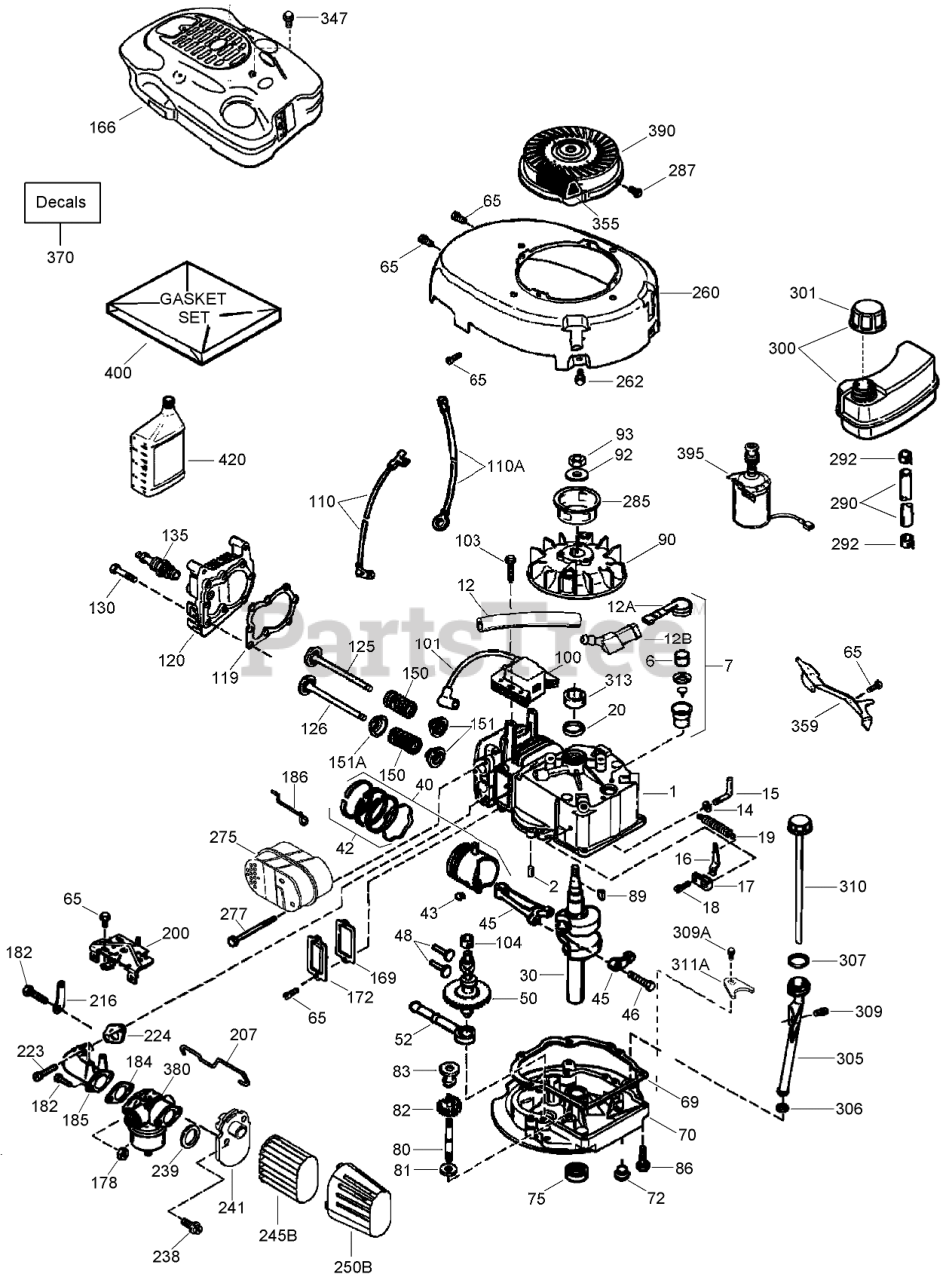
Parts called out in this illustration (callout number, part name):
1	Cylinder ASM (Includes 2, 20)
2	Pin-Dowel
6	Element-Breather
7	Breather ASM (Includes 6, 12A)
12	Tube-Breather
12A	Breather Cover and Tube ASM
12B	Elbow-Tube, Breather
14	Washer-Flat
15	Governor Rod ASM (Includes 14)
16	Lever-Governor
17	Clamp-Lever, Governor
18	Screw (T-15, 8-32 x 19/64)
19	Spring-Extension (Governor)
20	Seal-Oil
30	Crankshaft
40	Piston, Pin and Ring Set (.010 O S) (Includes 42)
40	Piston, Pin and Ring Set (STD) (Includes 42)
42	Ring Set (.010 O S)
42	Ring Set (STD)
43	Ring-Retaining, Piston Pin
45	Connecting Rod Asm (Includes 46)
46	Bolt-Rod, Connecting
48	Lifter-Valve
50	Camshaft (Exhaust M C R) (Includes 104)
52	Oil Pump ASM
65	Screw (10-24 x 9/16)
69	Gasket-Flange, Mounting
70	Mounting Flange Asm (Includes 72-83, 306, 309A, 311A)
72	Plug-Drain, Oil (Flush Mount)
75	Seal-Oil
80	Shaft-Governor
81	Washer-Flat
82	Governor Gear ASM (Includes 81)
83	Spool-Governor
86	Screw (1/4-20 x 1-1/4)
89	Key-Flywheel
90	Flywheel
92	Washer-Belleville
93	Nut-Flywheel
100	Ignition-State, Solid
101	Cover-Spark Plug
103	Screw (T-15, 10-24 x 15/16)
104	Bushing-Cam
110	Wire-Ground
110A	Ground Wire (11.25 With Ring Terminal & Female Straight Terminal)
119	Gasket-Head, Cylinder
120	Head-Cylinder
125	Valve-Exhaust (Std) (Includes 151)
126	Valve-Intake (STD) (Includes 151)
130	Screw (5/16-18x1-1/2)
135	Spark Plug-Resistor (R J19 L M)
150	Spring-Valve
151	Cap-Valve, Spring
151A	Seal-Valve, Intake
